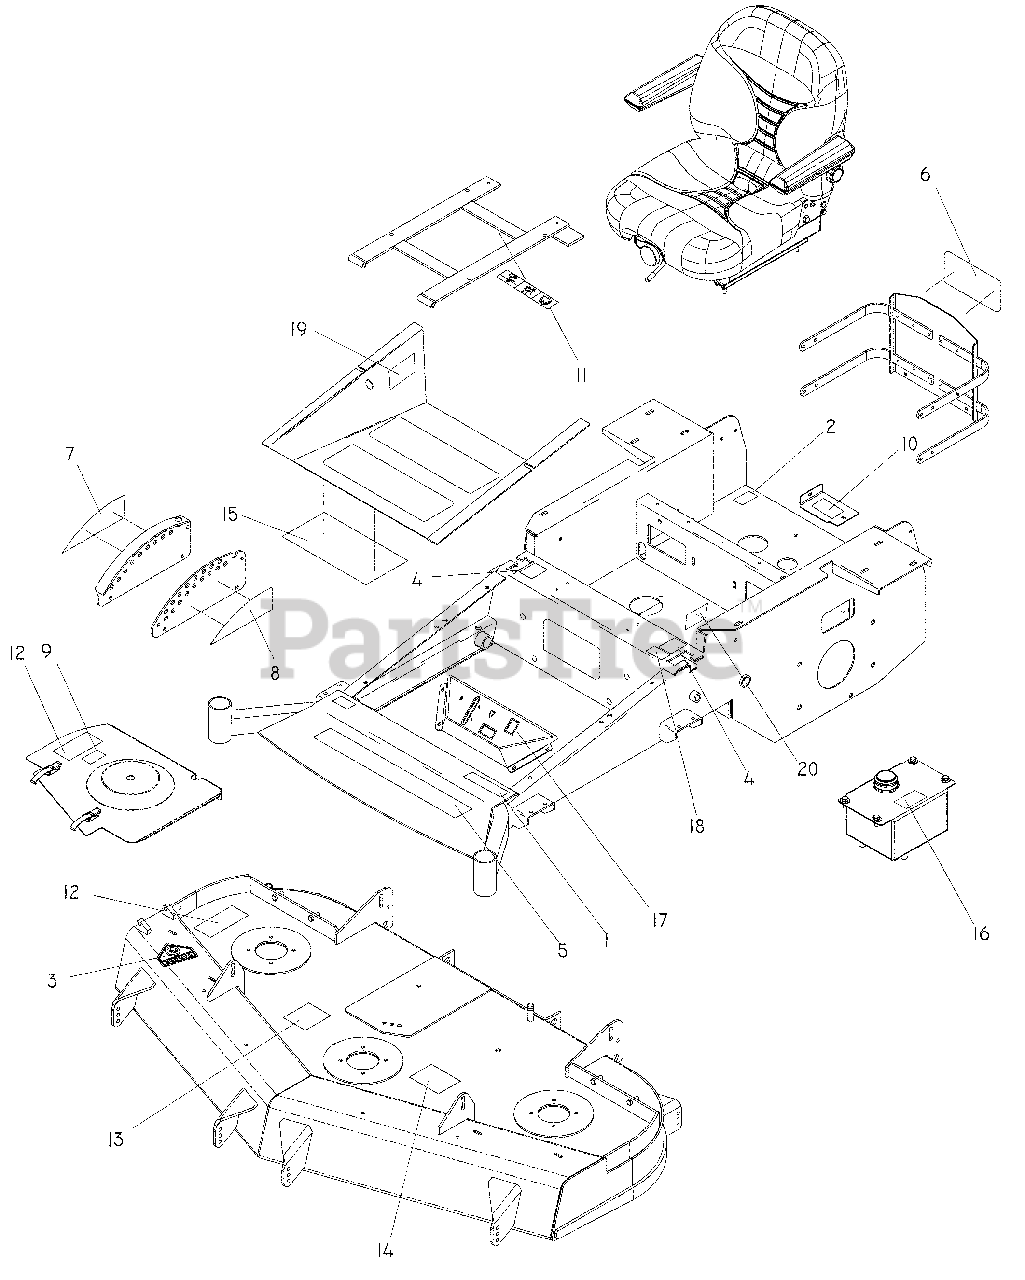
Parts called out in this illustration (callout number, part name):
1	DECAL, LZ5227
2	DECAL, PROP 65
3	DECAL, WARNING
4	DECAL, MOTION CONTROL
5	DECAL, HUSQVARNA
6	DECAL, HUSQVARNA CROWN
7	DECAL, HEIGHT INDICATOR
8	DECAL, HEIGHT INDICATOR
9	DECAL, NO STEP
10	DECAL, DANGER BELT DRIVE
11	DECAL, BATTERY WARNING
12	DECAL, SEVERING
13	DECAL, ANTI-SCALP
14	DECAL, BELT ROUTING
15	DECAL, SERVICE
16	DECAL, OIL TANK
17	DECAL, CONSOLE
18	DECAL, TRACKING
19	DECAL, WARNING
20	DECAL, RELAYS
